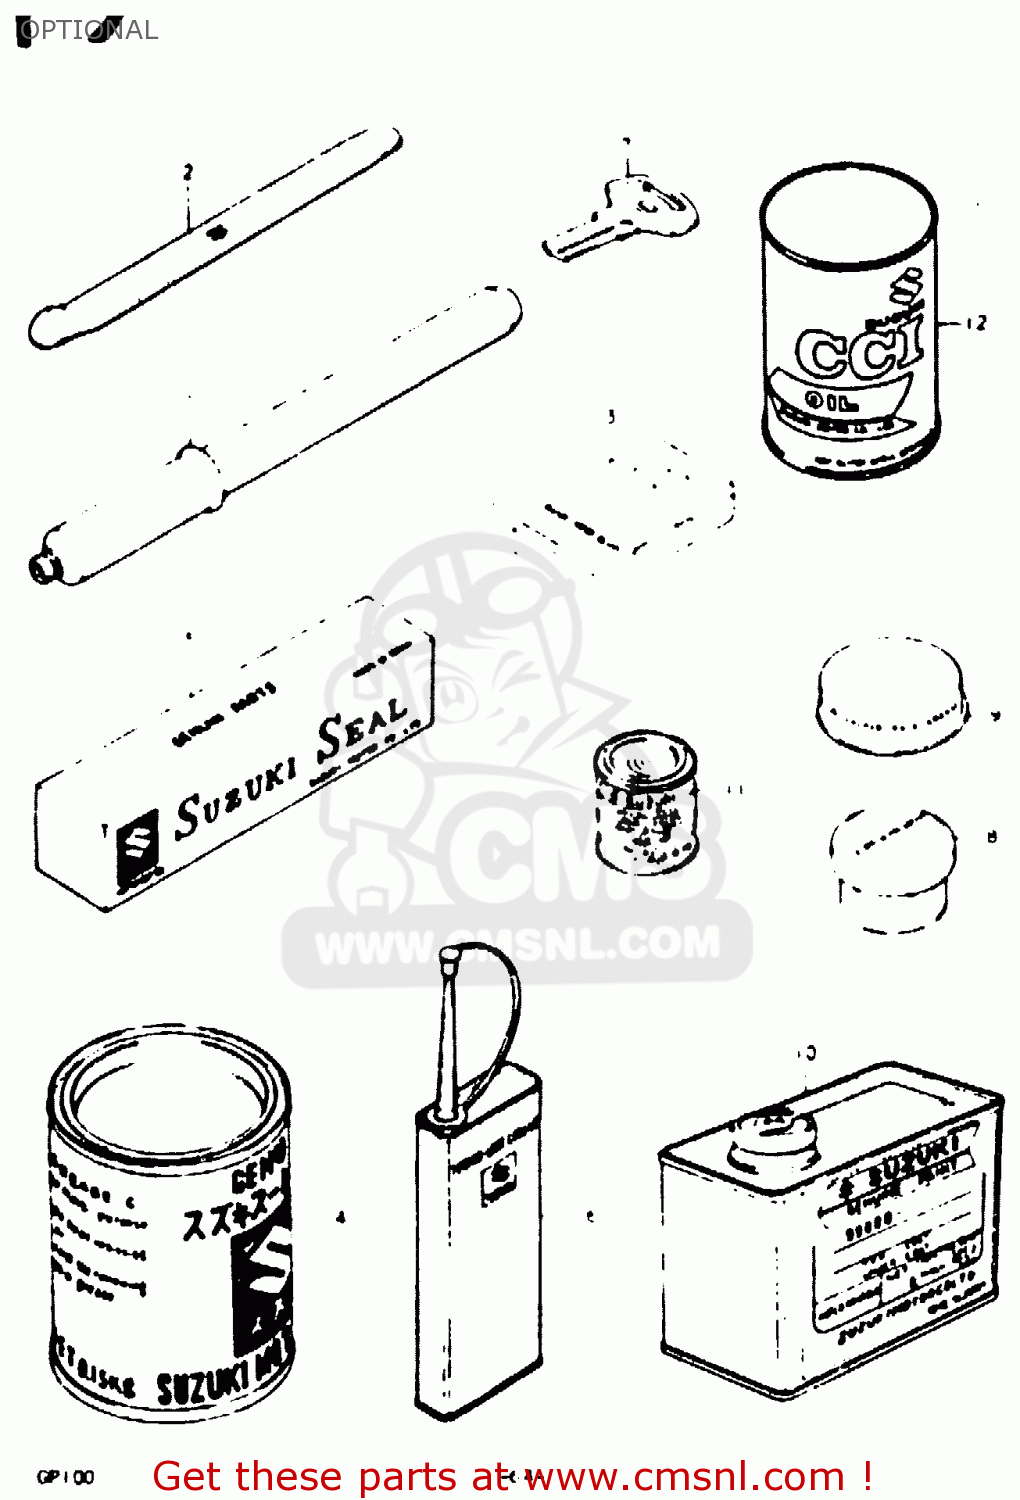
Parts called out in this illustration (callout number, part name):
1	INFLATOR, AIR
2	LEVER,TIRE
3	TUBE REPARING TOOL
4	GREASE(C)EP2 LITHIUM 150G
5	GASKET, LIQUID
6	THREAD LOCK NO.1401 CLEAR 200G
7	KEY,BLANK
10	PAINT (BLACK)
11	PAINT,BLACK
12	CCI OIL
